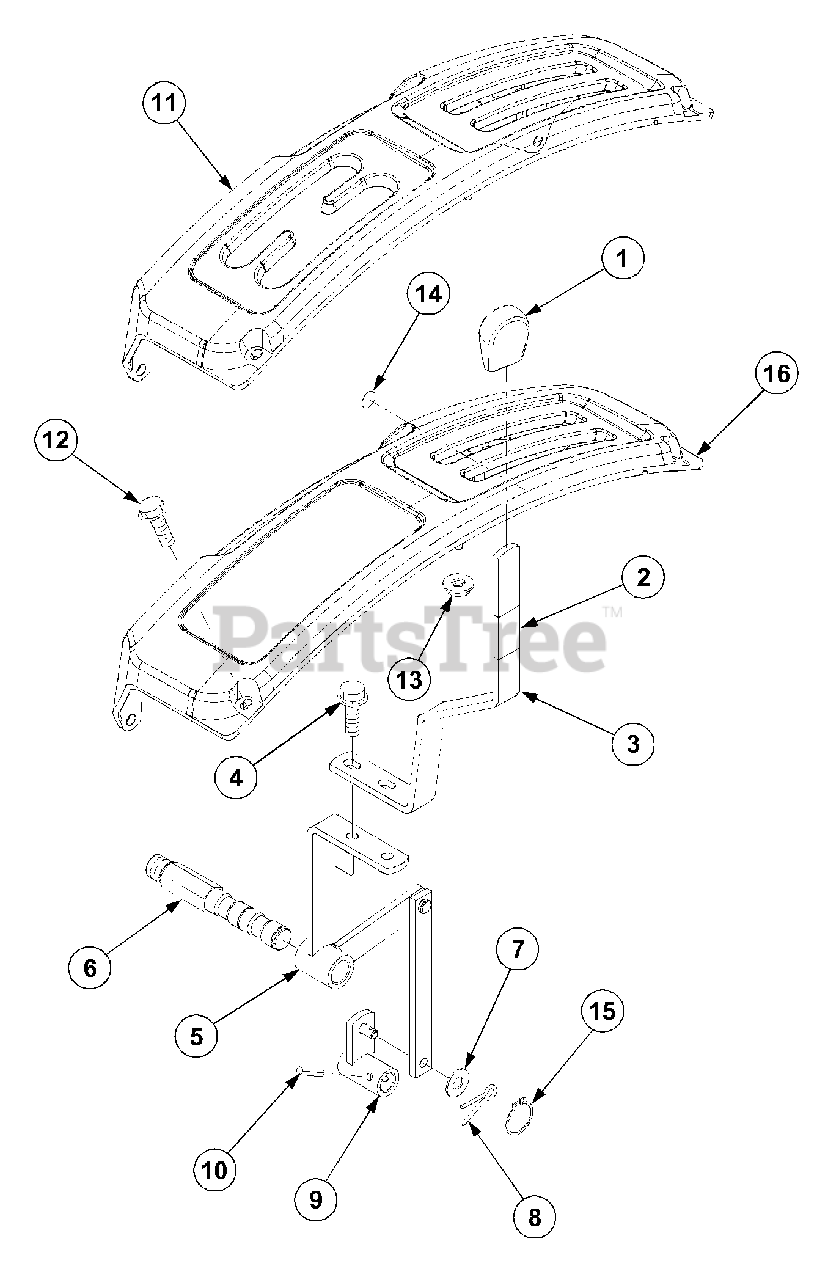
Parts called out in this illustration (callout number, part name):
3	Lever,Rear PTO
4	Bolt,w/Washer
9	Link,Rear PTO
11	Lever Guide LH
12	Bolt,w/Washer
16	Lever Guide LH
